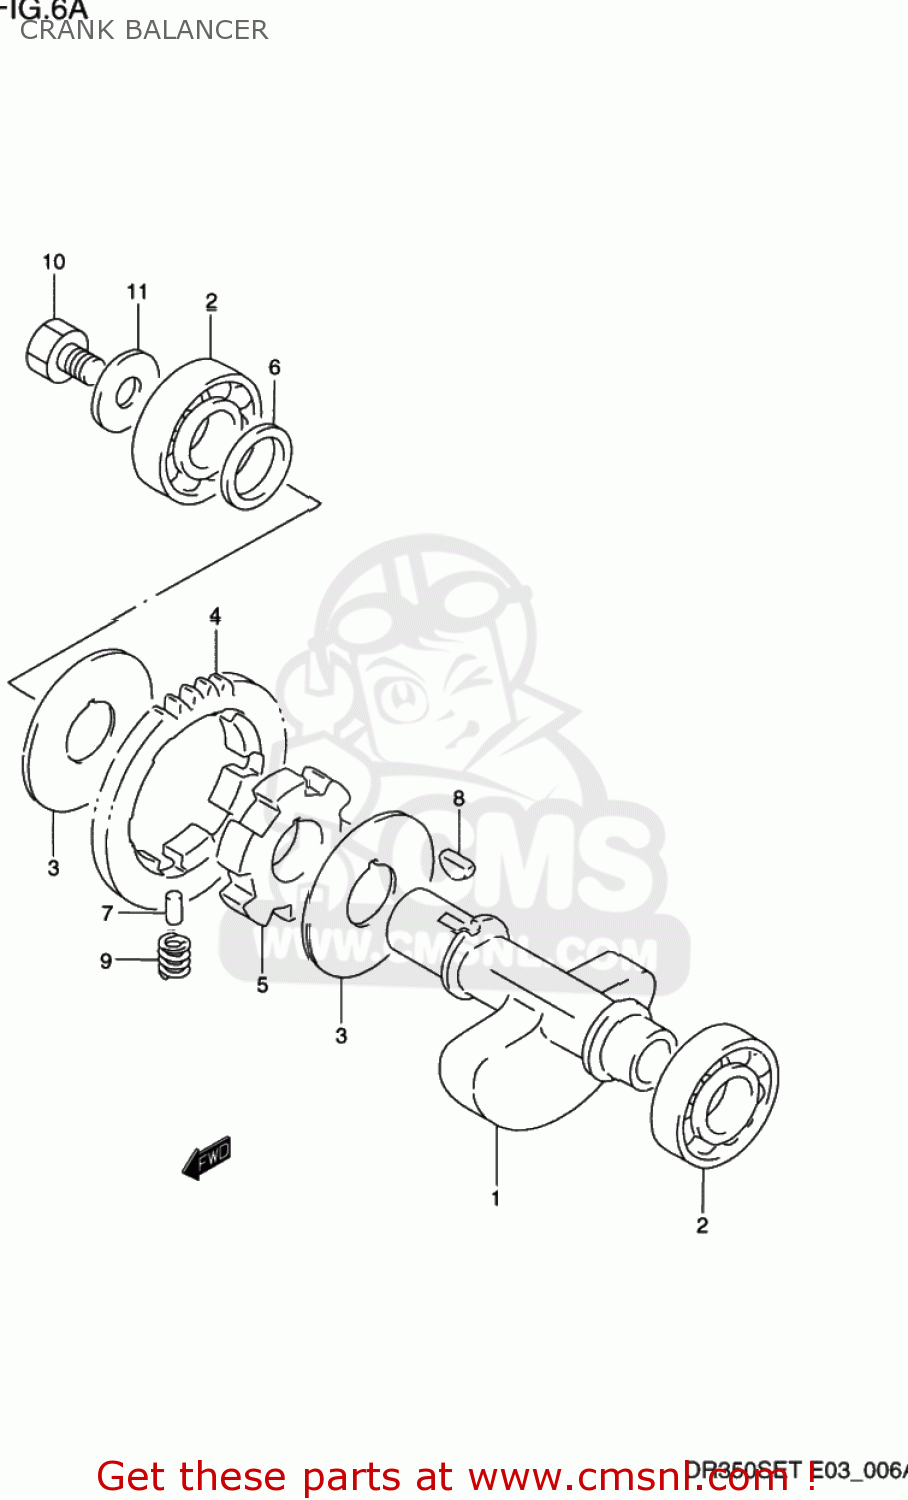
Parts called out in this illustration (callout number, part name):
1	BALANCER,CRANKSHAFT
2	BEARING(20X47X14)
3	WASHER
4	GEAR,CRANK BALANCER
5	RACE,CRANK BALANCER DRIVEN GEAR
6	THRUST WASHER
7	PIN
8	KEY
9	SPRING
10	BOLT
11	WASHER
